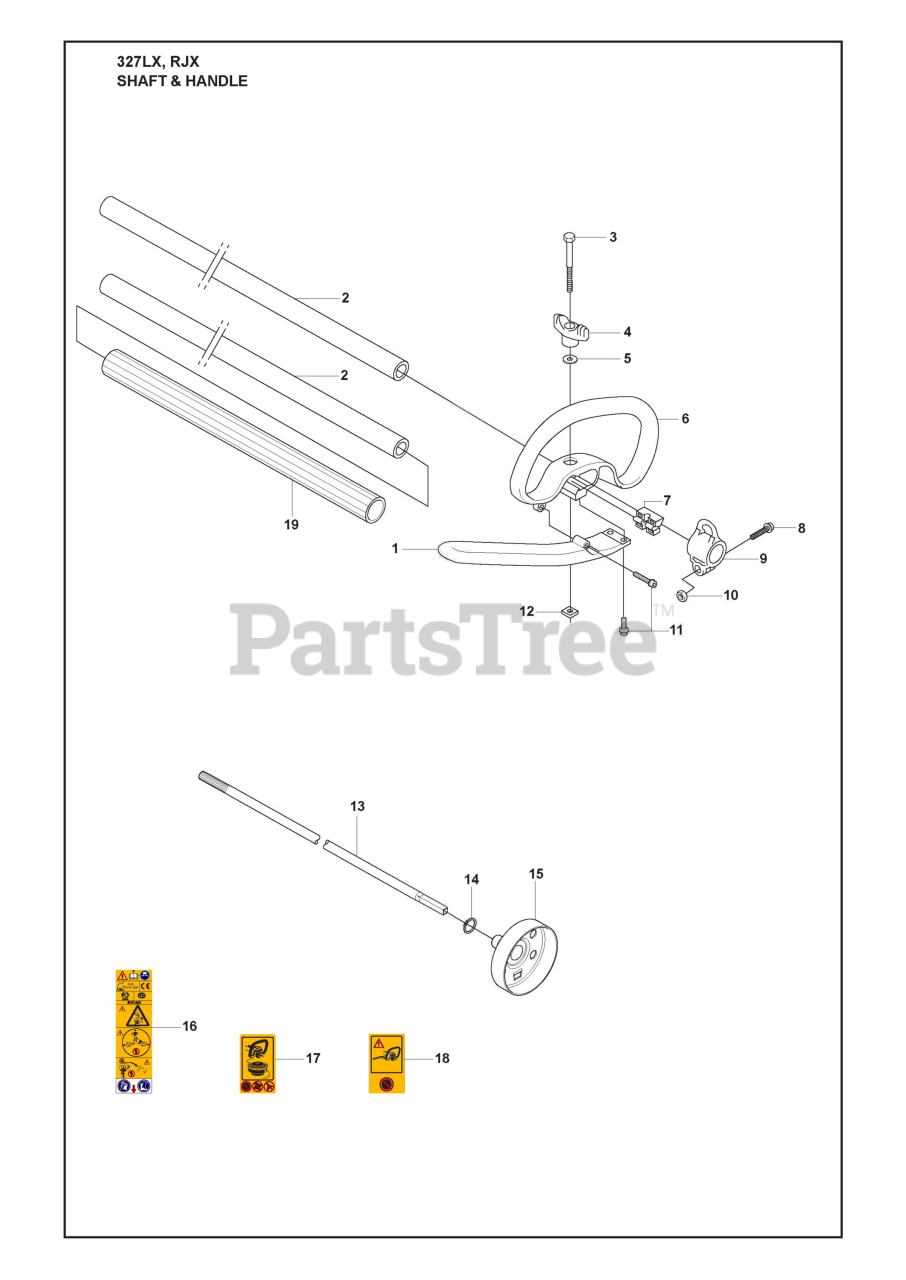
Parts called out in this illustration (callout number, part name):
1	HANDLE EXTENSION
2	DRIVE TUBE ASSEMBLY
2	TUBE DRIVESHAFT ASSY
3	SCREW
3	SCREW M6X50
4	KNOB
5	WASHER
6	RP HANDLE, LOOP
6	%HANDLE, LOOP
7	SPACER PLASTIC
8	SCREW
9	HARNESS HOLDER
10	NUT
11	SCREW
13	DRIVE SHAFT
14	RETAINING RING SGA 10
15	CLUTCH DRUM
16	RP WARNING DECAL
17	DECAL WARNING "NO BLADES"
18	DECAL
19	GRIP
